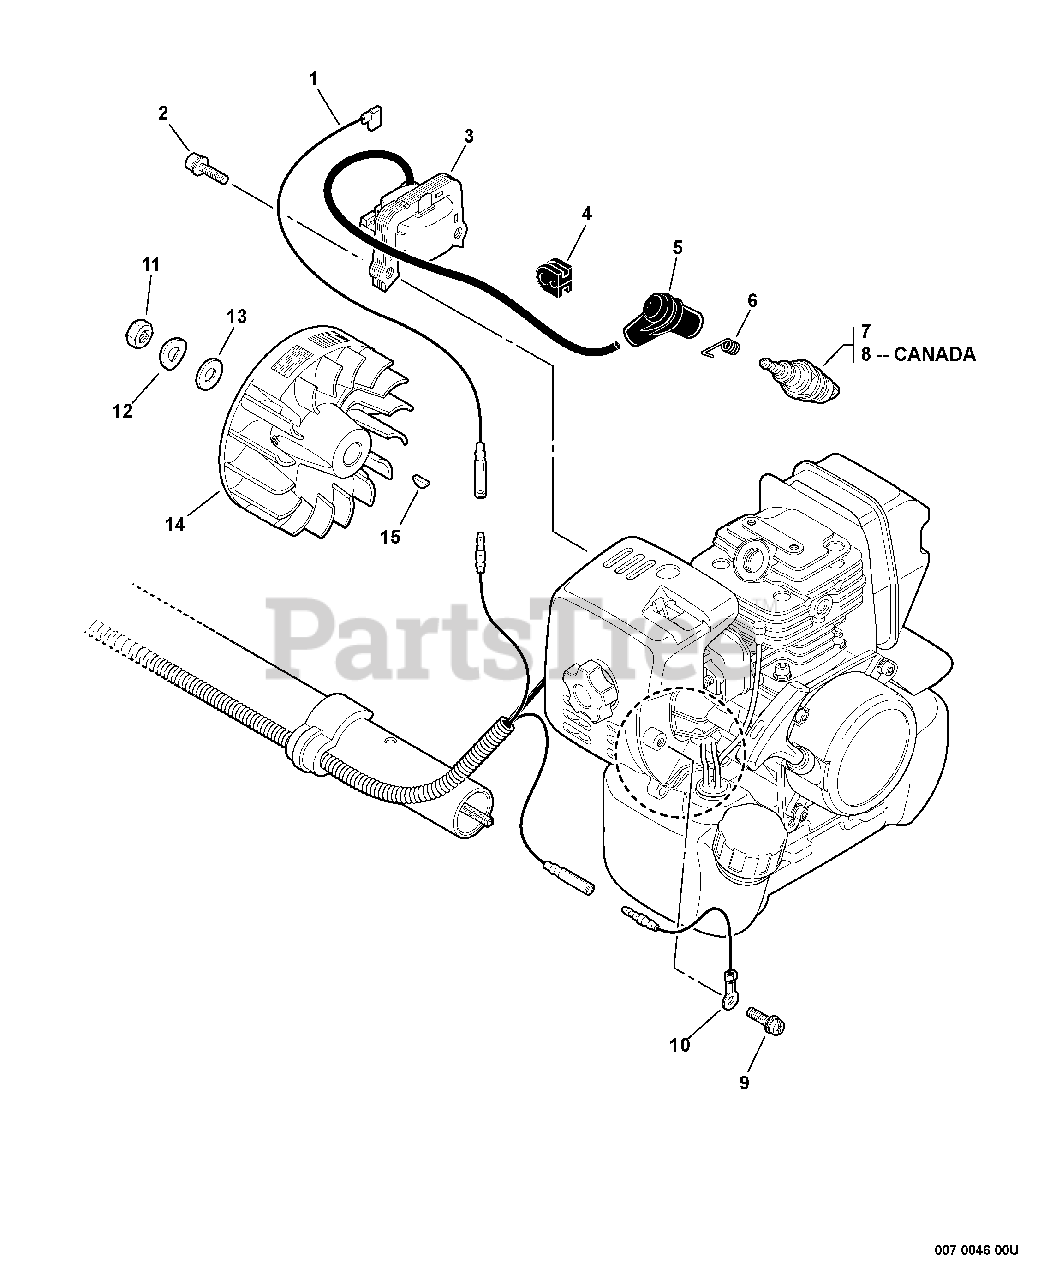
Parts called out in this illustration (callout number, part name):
1	LEAD - IGNITION
2	SCREW - 5X20
3	COIL, IGNITION
5	CAP, SPARK PLUG
6	TERMINAL, SPARK PLUG CAP
7	SPARK PLUG -- BPM-8Y
8	SPARK PLUG -- BPMR-8Y
9	SCREW - 5X10
10	LEAD - GROUND
12	LOCKWASHER - 8
13	WASHER - 8
14	FLYWHEEL
